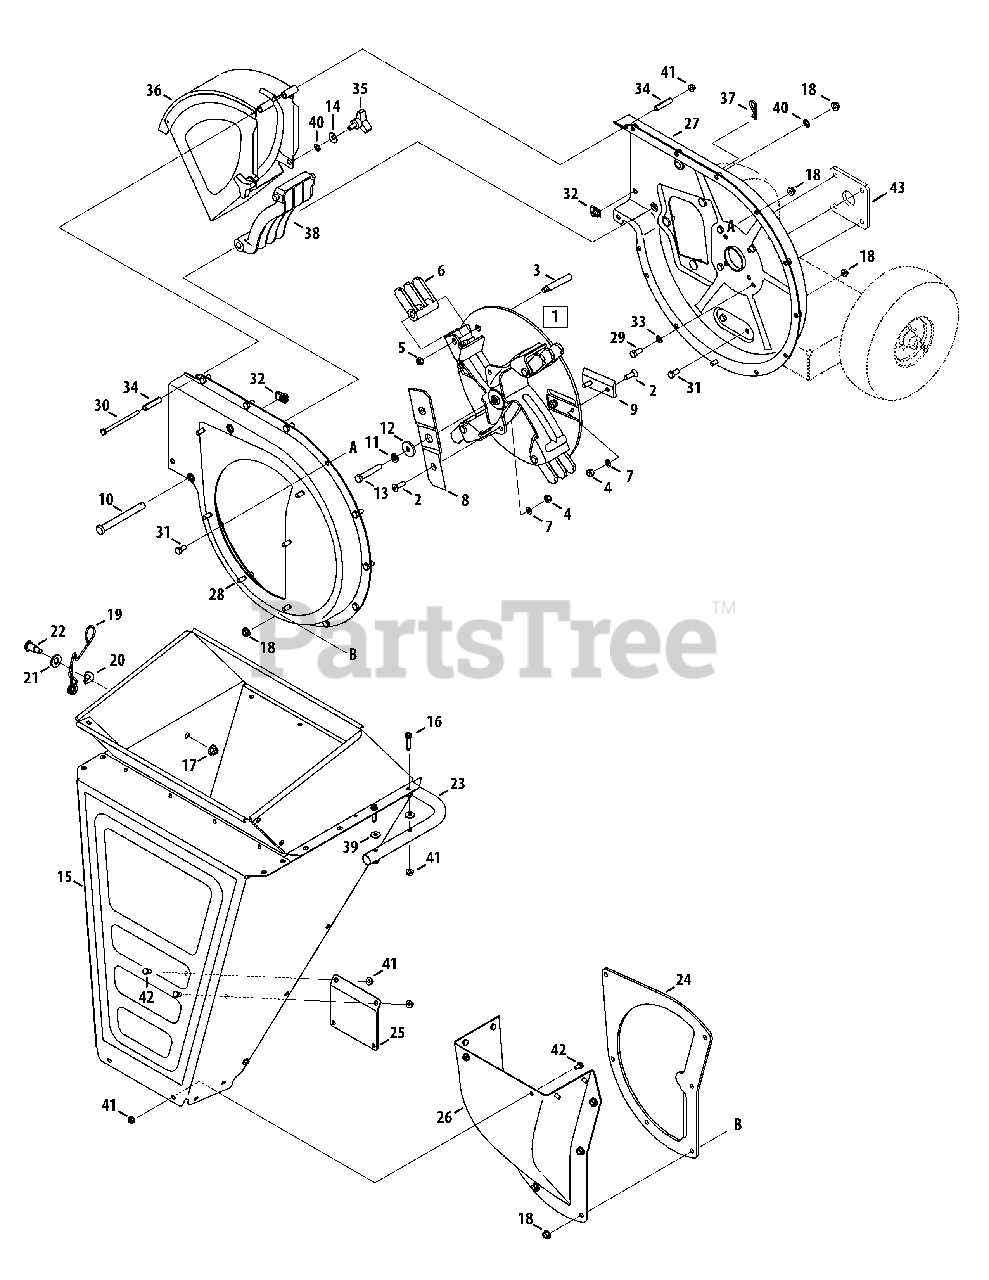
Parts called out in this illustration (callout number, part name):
1	Impeller Assembly Complete
2	Machine Screw, 5/16-24 x 1.0
3	Shoulder Pin, .5 x 2.625
4	Hex Lock Nut, 5/16-24
5	Nut, Jam Lock, 3/8-16
6	Flail Blade
7	Lock Washer, 5/16
8	Shredder Blade
9	Chipper Blade
10	Clevis Pin,.50 x 4.62
11	Lock Washer, 3/8
12	Flat Washer,.406 x 1.25
13	Hex Cap Screw, 3/8-24 x 2.2
14	Bell Washer.340 ID x.872 OD
15	Shredder Hopper Assembly
16	Hex Cap Screw, 1/4-20 x 1.250
17	Flange Lock Nut, 3/8-16
18	Flange Lock Nut, 5/16-18
19	Torsion Spring
20	Spring Washer,.50 x 1.0 x.022
21	Flat Washer,.50 x 1.0 x.0125
22	Shoulder Screw, 3/8-16,
23	Hopper Handle
24	Shredder Plate
25	Hopper Support Bracket
27	Inner Flail Housing Assembly
28	Outer Flail Housing Assembly
29	Hex Cap Screw, 5/16-24 x .75
29	Hex Cap Screw 5/16-24 x 1.00
30	Hex Cap Screw, 1/4-20 x 3.75
31	Hex Cap Screw, 5/16-18 x .625
32	U-Nut, 5/16-18
33	Lock Washer, 5/16
34	Hinge Spacer,.265 x.380 x 1.66
35	Knob, 5/16-18
36	Chute Deflector Assembly
37	Internal Cotter Pin
38	Shredder Screen
39	Flat Washer, .28 x .74 x .063
40	Speed Nut,.3125ID
41	Nut, Flange, Lock, 1/4-20
42	TT Screw, 1/4-20 x .5
43	Engine Plate
